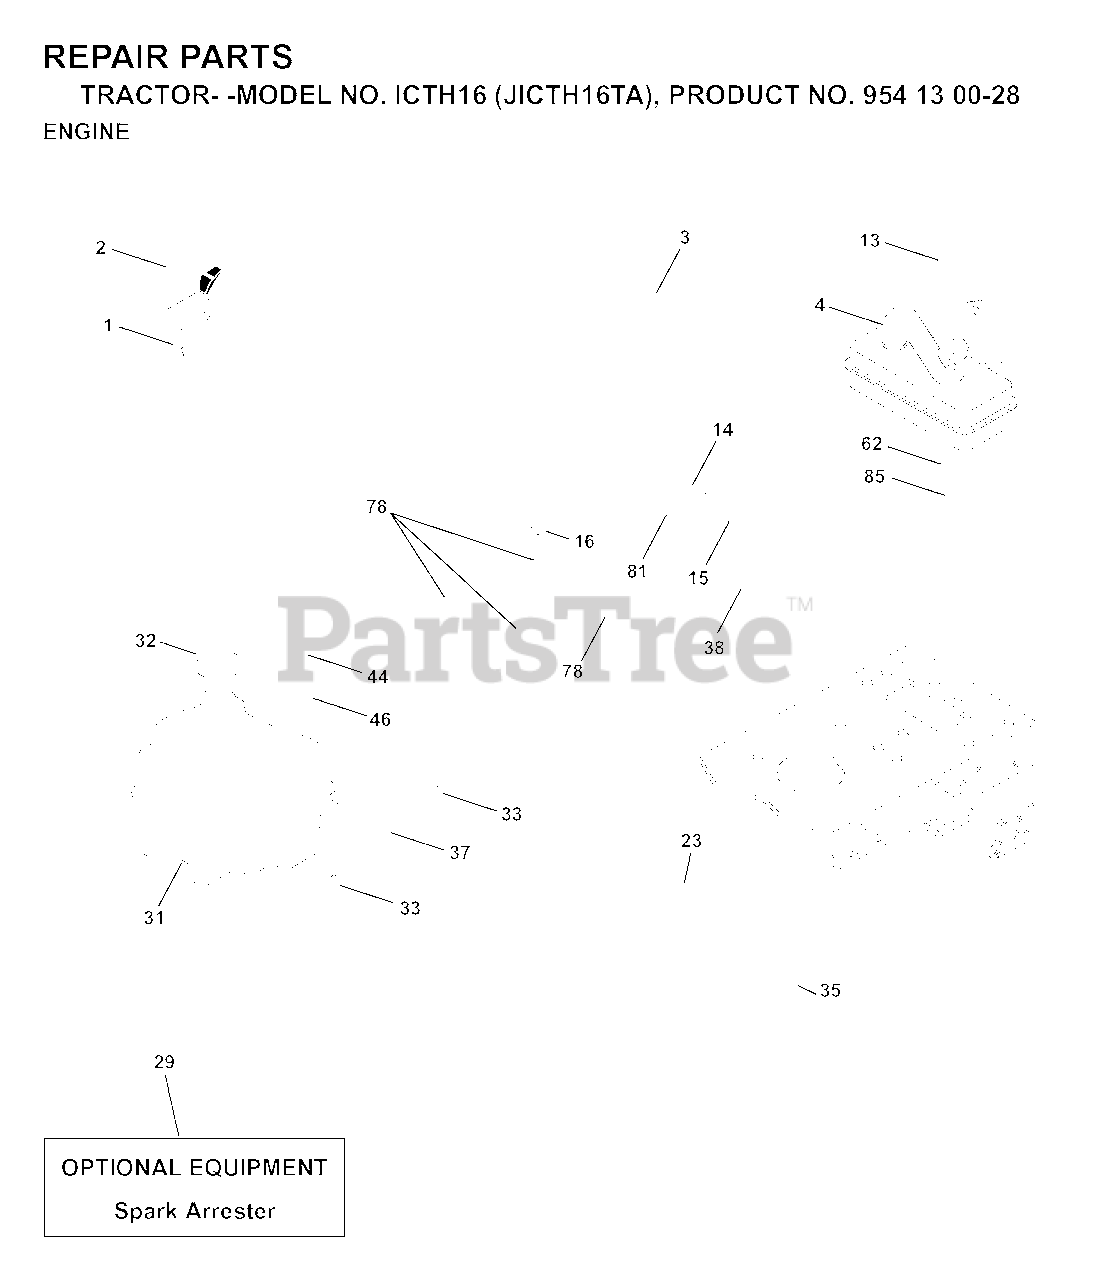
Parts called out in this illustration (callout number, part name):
1	CHOKE CONTROL
2	SCREW LT
14	PIPE NIPPLE
15	ELBOW
16	LOCKWASHER
23	PROTECTOR
29	ARRESTER SPARK (OPTIONAL)
31	FUEL TANK
32	FUEL CAP
33	HOSE CLAMP
35	SCREW
37	LINE.FUEL.20
44	SCREW HEX CRT
62	LOCKWASHER
78	SCREW
81	NUT FLANGE 1/4-20 STARTER NUT
